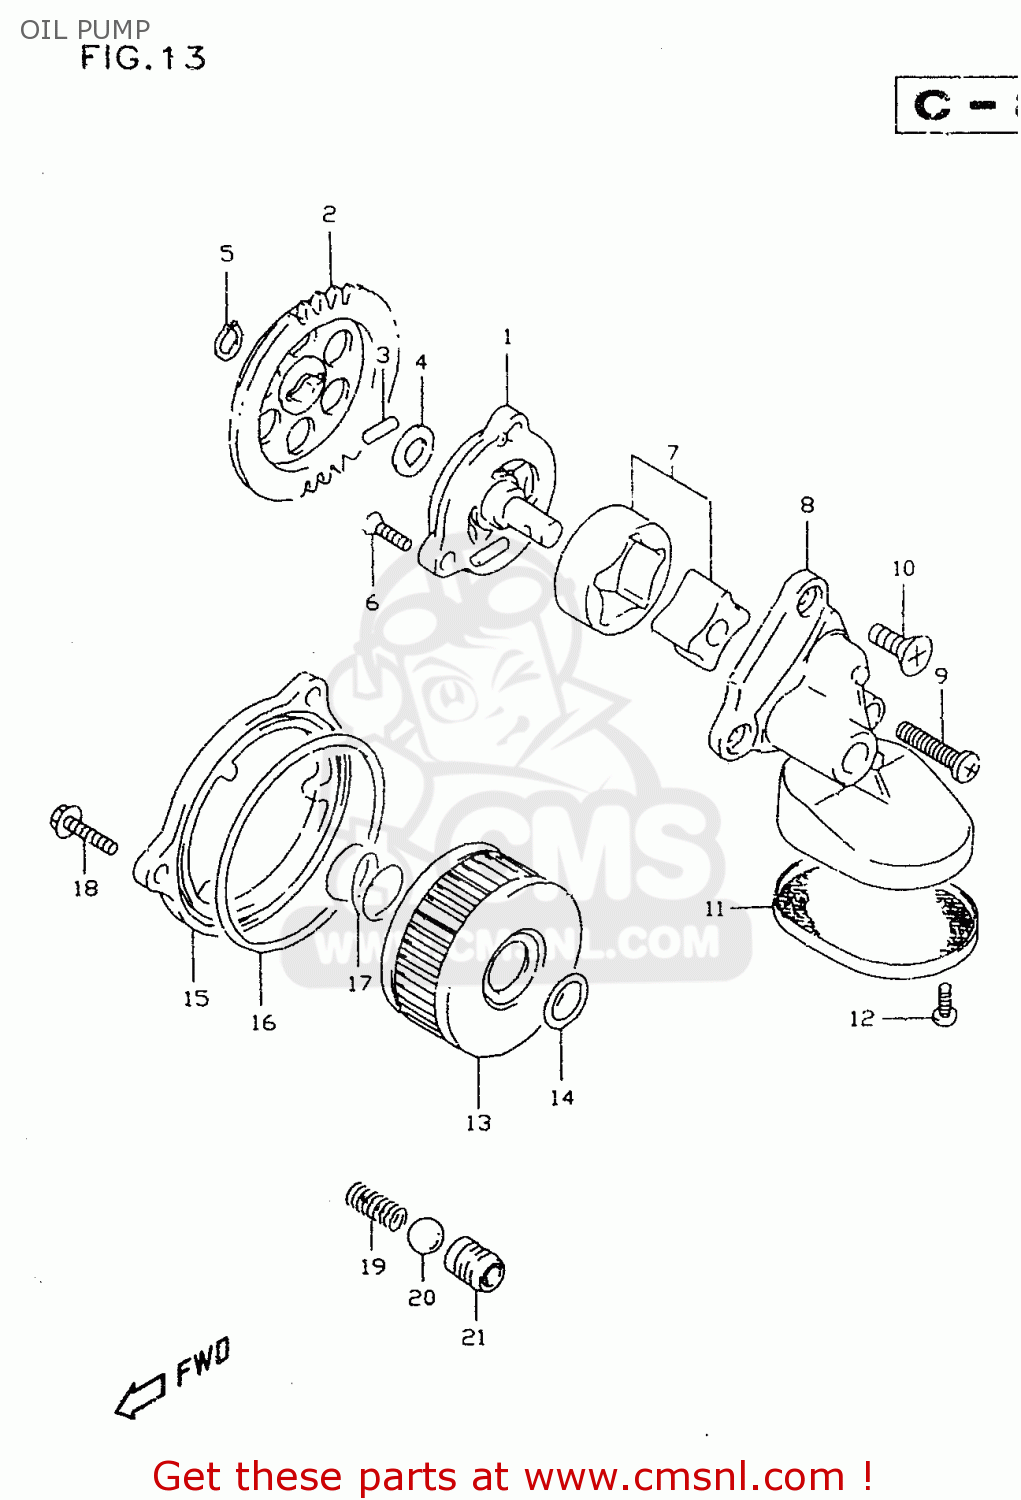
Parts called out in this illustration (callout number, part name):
1	PUMP ASSY,ENGINE OIL NO.1
2	GEAR,OIL PUMP DRIVEN
3	PIN(4X15.8)
4	SHIM
5	CIRCLIP,10MM
6	SCREW ,6X16
7	ROTOR SET,OIL PUMP,NO.2
8	COVER,OIL PUMP NO.2
9	SCREW 6X30
10	SCREW ,6X16
11	STRAINER,OIL PUMP NO.2
12	SCREW
13	FILTER ASSY,ENGINE OIL
14	O RING(D:2.4,ID:15.8)
15	CAP,OIL FILTER
16	O RING(D:2.4,ID:73)
17	SPRING
18	SCREW
19	SPRING
20	BALL
21	SEAT,OIL CHECK VALVE
